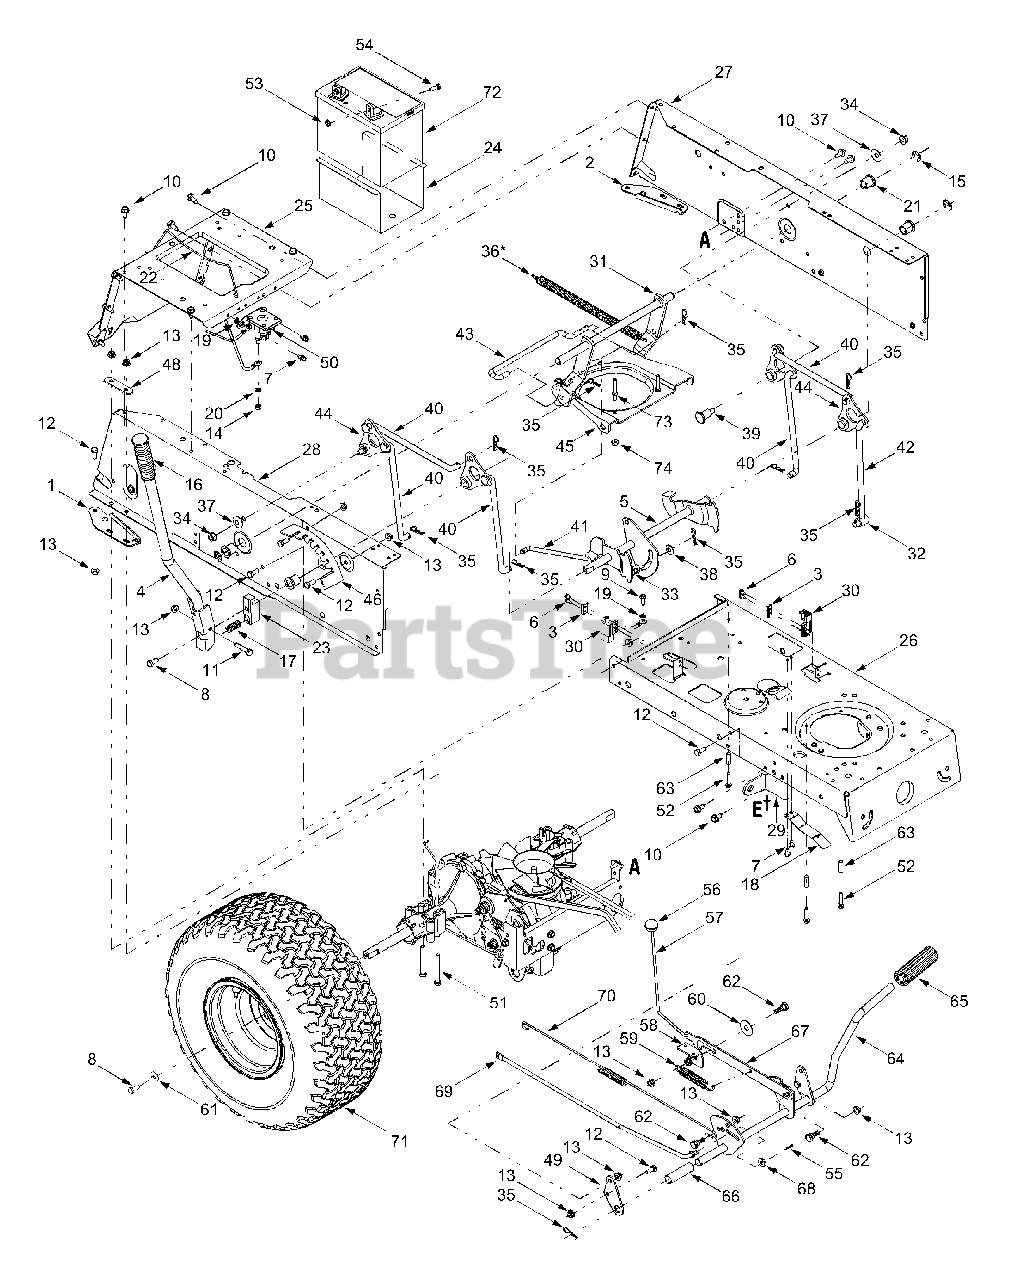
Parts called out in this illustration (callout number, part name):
6	Self-tapping Screw, #10-16 x .5
7	Self-tapping Screw, 1/4-20 x .5
8	Hex Cap Screw, 5/16-24 x .75
9	Self-tapping Screw, 1/4-20 x .75
10	Self-tapping Screw, 5/16-12 x .75
11	Hex Cap Screw, 5/16-18 x 1.5
12	Hex Screw, 5/16-18 x .75
13	Flange Lock Nut, 5/16-18
14	Hex Nut, 1/4-20
15	E-Ring, .625 Dia Shaft
16	Handle Grip
17	Compression Spring, .55 x 1.37
18	Switch Actuator Spring
19	External Lock Washer, 1/4
20	Lock Washer, 1/4
21	Flange Bearing, .632 ID
22	Battery Hold-down Rod
23	Lift Shaft Connector
33	Ferrule, 3/8-24 x .375
34	Flange Lock Nut, 3/8-16
35	Internal Cotter Pin, .080 x 1.56
36	Extension Spring, .76 x 13
37	Bell Washer, .389 x 1.12 x .030
38	Flat Washer, .385 x .87 x .060
39	Shoulder Bolt, 3/8-16 x .62 x .92
40	Deck Hanger Link
41	Deck Disengagement Rod
42	Deck Hanger Link
43	Rear Stabilizer Rod
44	Lift Link
51	Hex Cap Screw, 5/16-18 x 2.75
52	Self-tapping Screw, 1/4-20 x 1.25
53	Hex Sems Nut, 1/4-20
54	Hex Screw,1/4-20 x .75
55	Cotter Pin, 1.0
57	Brake Lockout Rod
59	Extension Spring, 4.31
60	Flat Washer, .442 x 1.38 x .060
61	Bell Washer, .34 x .872 x .060
62	Shoulder Screw, .437 x .286
63	Spacer, .260 x .372 x 1.030
66	Spacer, .640 x .76 x 2.63
67	Brake Lockout Bracket
68	Flat Washer, .344 x .750 x .120
69	Extension Spring, 22.16
72	Battery, 270 CCA
73	Flange Lock Nut, 1/4-20
74	Belt Guard Pin, 1/4-20
